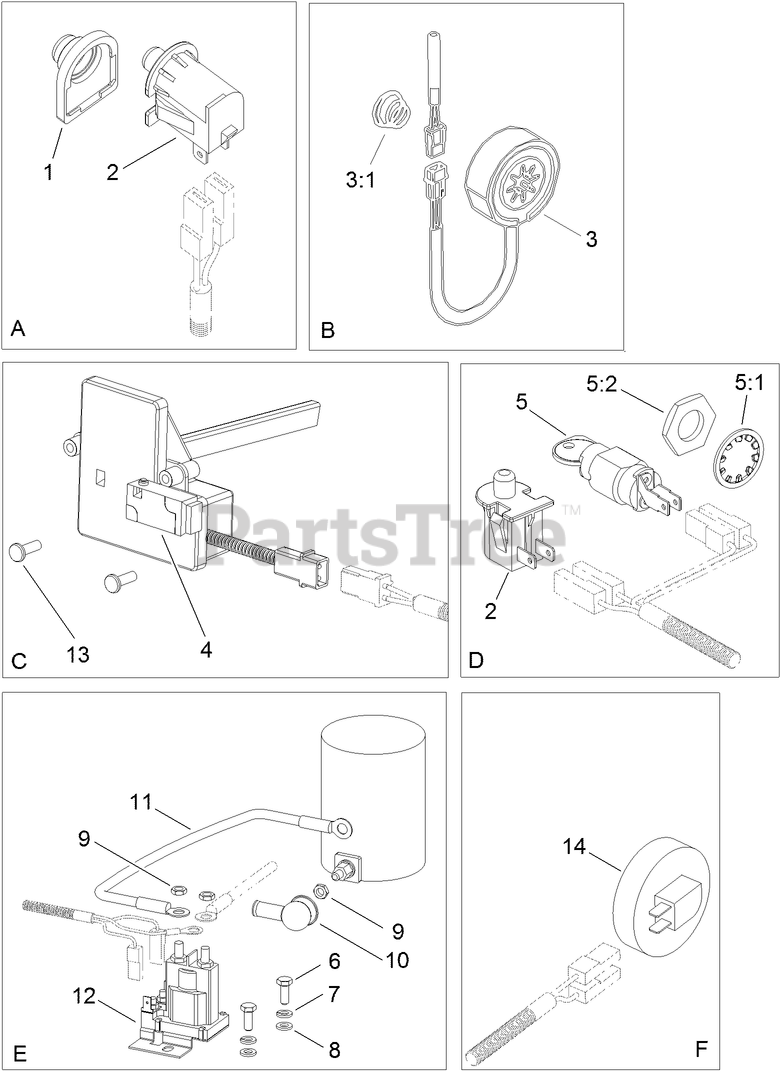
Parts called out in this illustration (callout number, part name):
1	COVER-PROTECTIVE
2	SWITCH-DELTA
3	MAGNET ASM
3:1	SPRING-COMPRESSION
4	SWITCH-OMRON
5	STARTER SWITCH ASM
5:1	WASHER-LOCK
5:2	NUT-HH
6	SCREW-HH
7	WASHER-SPRING
8	WASHER-FLAT
9	NUT-HHF
10	BOOT-RUBBER
14	SWITCH-SEAT
